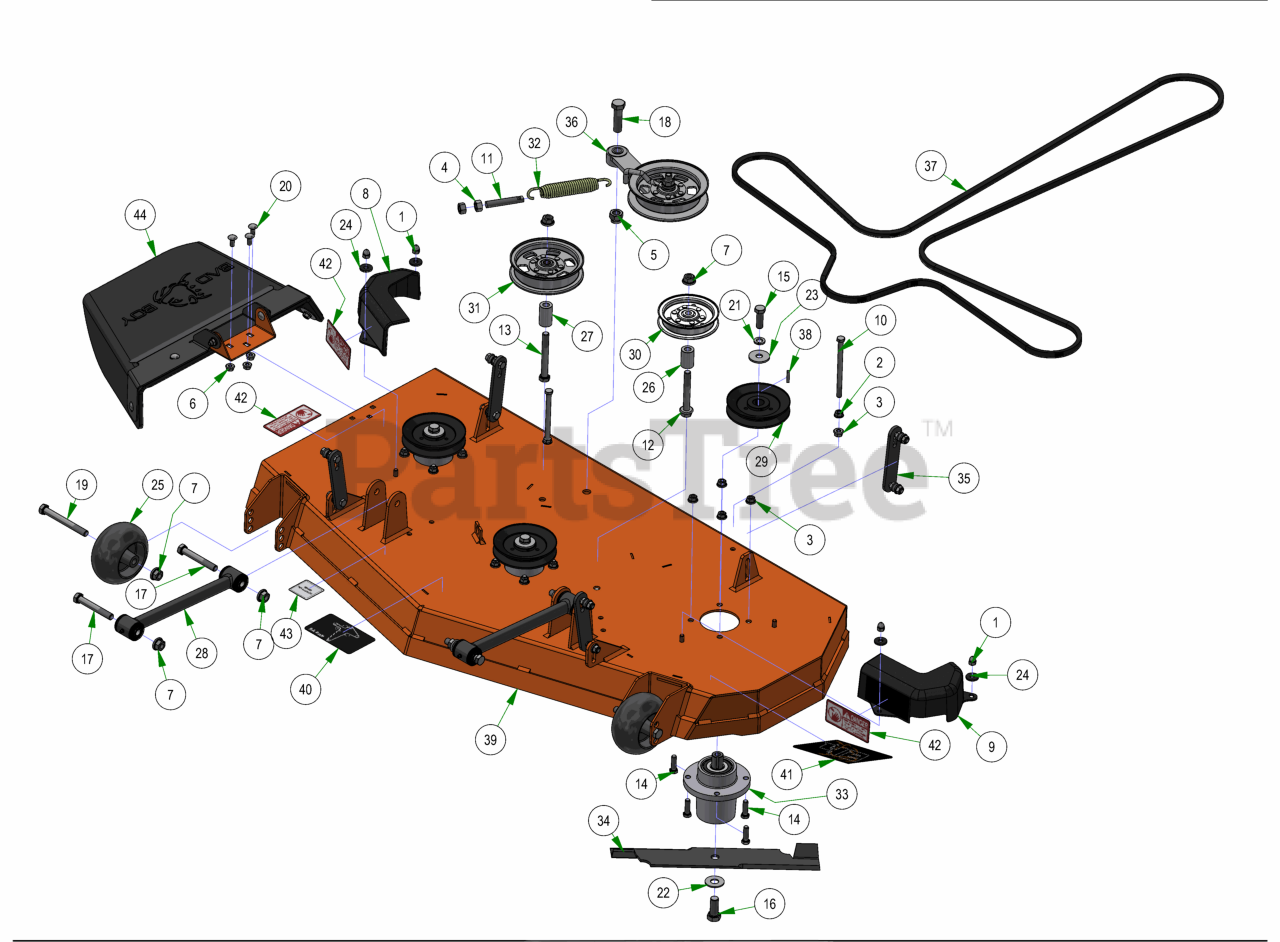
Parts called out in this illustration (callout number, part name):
1	5/16-18 ACORN NUT HIGH-CROWN ZC
2	3/8-16 HEX SERRATED FLANGE NUT HARD/ZINC
3	3/8-16 NYLON INSERT FLANGE LOCKNUT (GR.F) ZINC
4	1/2-13 HEX NUT ZINC
5	5/8-11 NYLON INSERT LOCKNUT ZINC
6	5/16-18 NYLON INSERT FLANGE LOCKNUT ZINC
7	1/2-13 NYLON INSERT FLANGE LOCKNUT ZINC
8	Pulley Cover Chute Side
9	Pulley Cover Non-Chute Side
10	3/8-16 X 5-1/4 HEX CAP SCREW (GR.5) ZINC
11	All Thread
12	1/2-13 X 3-1/2 HEX FLANGE BOLT (GR.8) ZINC
13	1/2-13 X 4 HEX CAP SCREW (GR.8) ZINC YELLOW
14	3/8-16 X 1-1/4 HEX CAP SCREW (GR.5) ZINC
15	1/2-20 X 1-1/2 HEX CAP SCREW (GR.5) ZINC
16	5/8-18 X 1-1/2 HEX CAP SCREW (GR.8) ZINC YELLOW
17	1/2-13 X 3-1/2 HEX CAP SCREW (GR.5) ZINC
18	5/8-11 X 2-1/4 HEX CAP SCREW (GR.5) ZINC
19	1/2-13 X 4-1/2 HEX CAP SCREW (GR.5) ZINC
20	5/16-18 x 3/4 Carriage Bolt
21	1/2 SPLIT LOCKWASHER (GR.8) ZINC/YELLOW
22	5/8 USS FLAT WASHER (1-3/4" OD) GR.8 ZINC YELLOW
23	1/2 BELLEVILLE WASHER (1-5/8 OD X .140 THK) ZINC
24	.360 ID X .983 OD X .120 THICK FLAT WASHER NYLON BLACK
25	2019 Deck Wheel
26	.502 ID X .750 OD X 1.500 Long Spacer
27	1 3/4" Pulley Spacer
28	Hybrid Turnbuckle/Deck Locator
29	MZ Deck Pulley
30	4 3/4" Idler Pulley
31	5-3/4 Idler Pulley
32	Deck Idler Spring
33	Spindle Assembly-MZ
34	48" High Lift Fusion Blade-MZ
35	Deck Hanger Assembly
36	Maverick HD & Down Deck Idler Assembly
37	B147 Deck Belt
38	3/16 X 1 SQ MACHINERY KEY 1018 STL ZINC
39	2025 48" x 4" Deck
40	2017 MZ Magnum 48"/42" Deck Route Decal
41	48" Grip Deck Decal
42	Danger Decal-Spindle/Discharge
43	Deck Impact Patent Decal 9591803
44	MZ Discharge Chute Assembly
